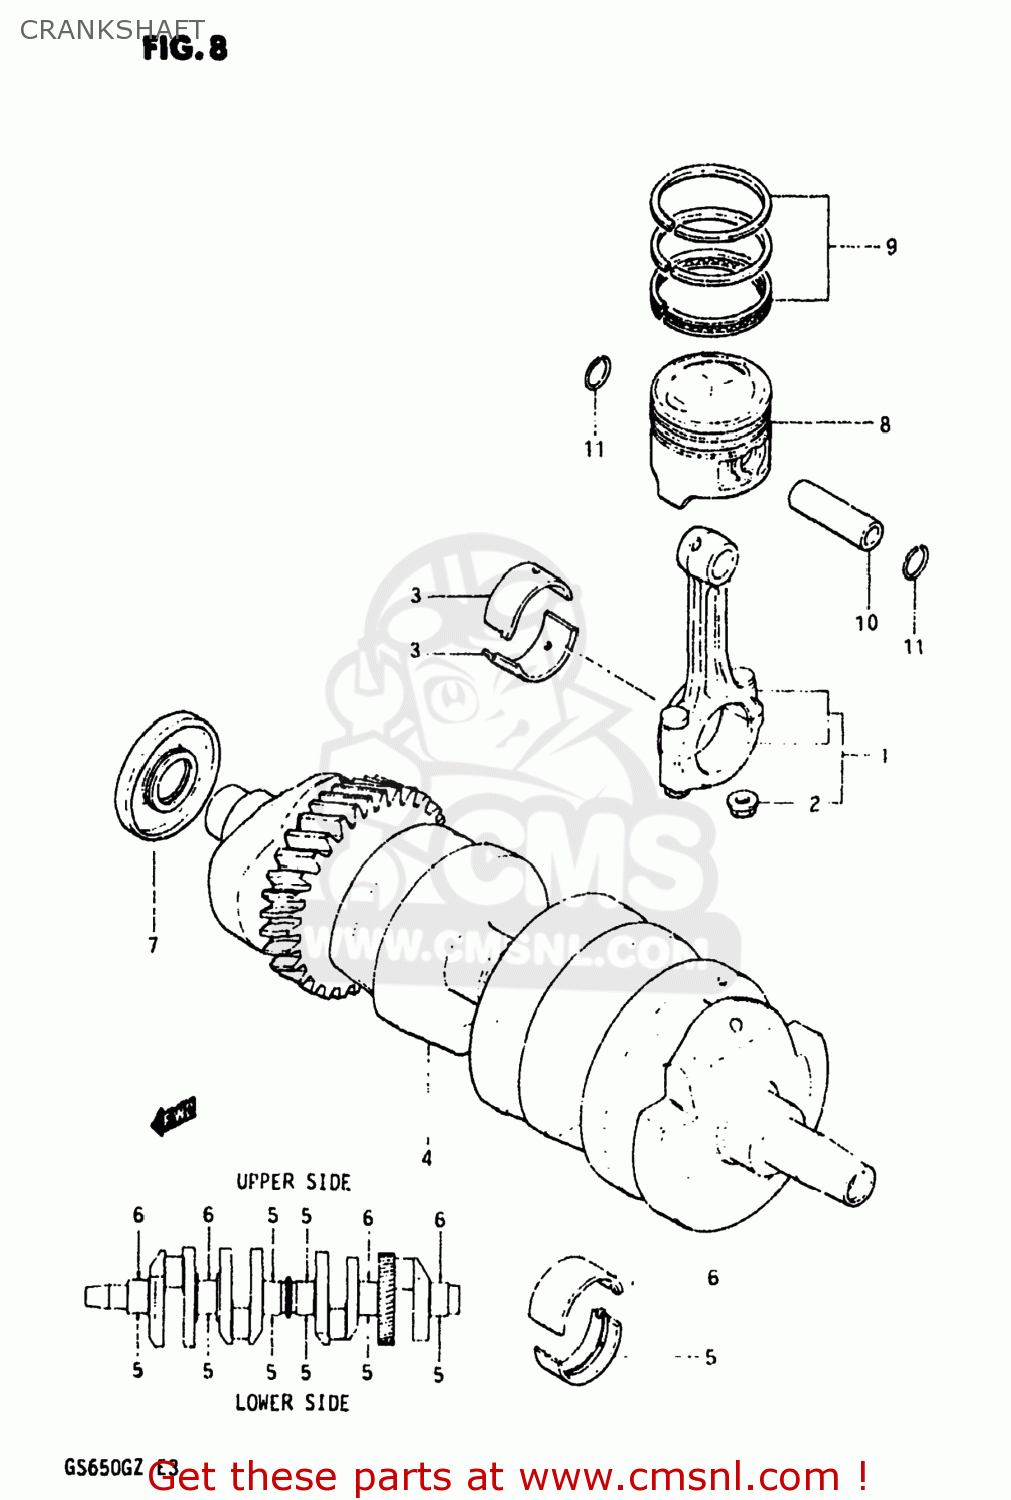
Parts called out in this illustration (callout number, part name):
1	ROD ASSEMBLY,CONNECTING
2	NUT
3	BEARING,CRANK PIN
4	CRANKSHAFT
5	METAL CRANKSHAFT
6	METAL CRANKSHAFT
7	OIL SEAL
8	PISTON
9	RING SET,PISTON
10	PIN,PISTON
11	CIRCLIP
